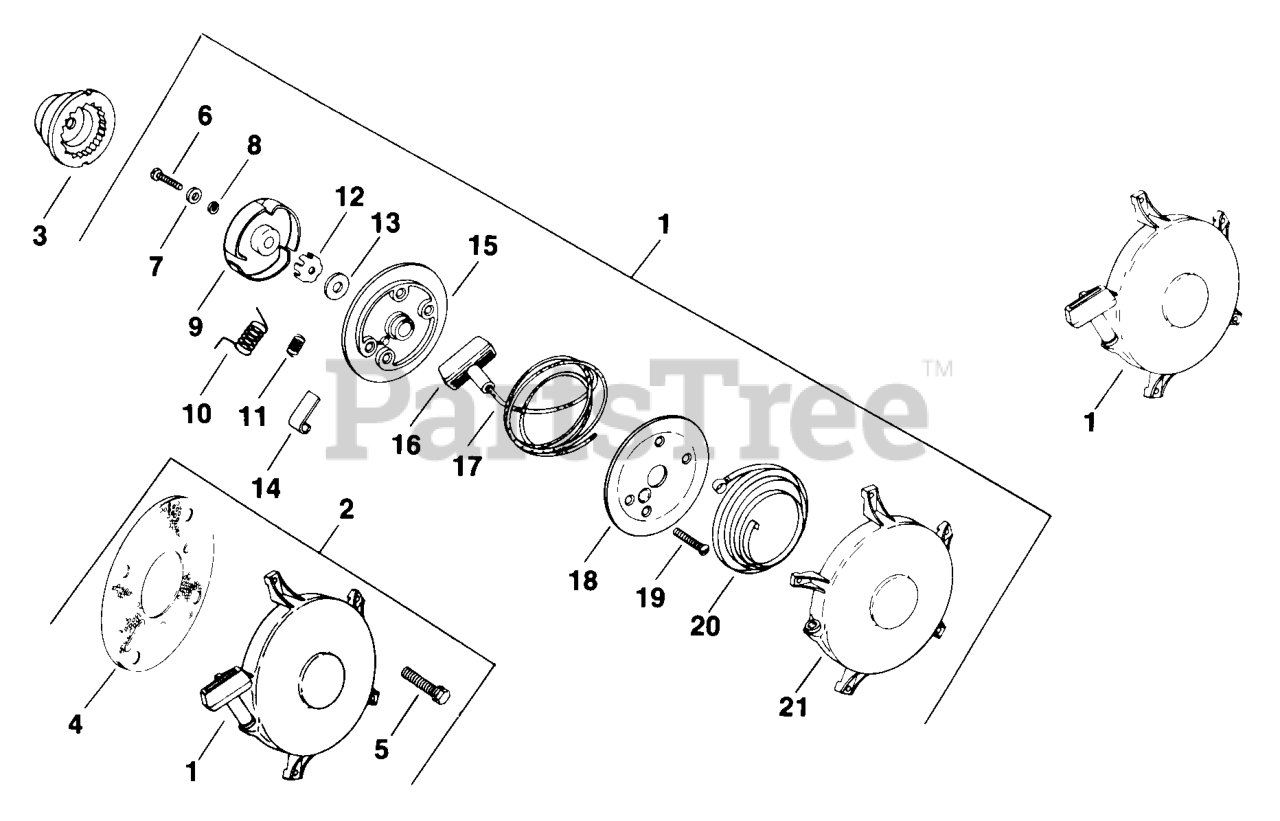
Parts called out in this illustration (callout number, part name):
3	HUB - DISCONTINUED
7	WASHER - DISCONTINUED
9	RETAINER
11	SPRING - DISCONTINUED
14	DOGS - DISCONTINUED
16	HANDLE - USE 25 166 01
17	ROPE - DISCONTINUED
21	HOUSING - DISCONTINUED
